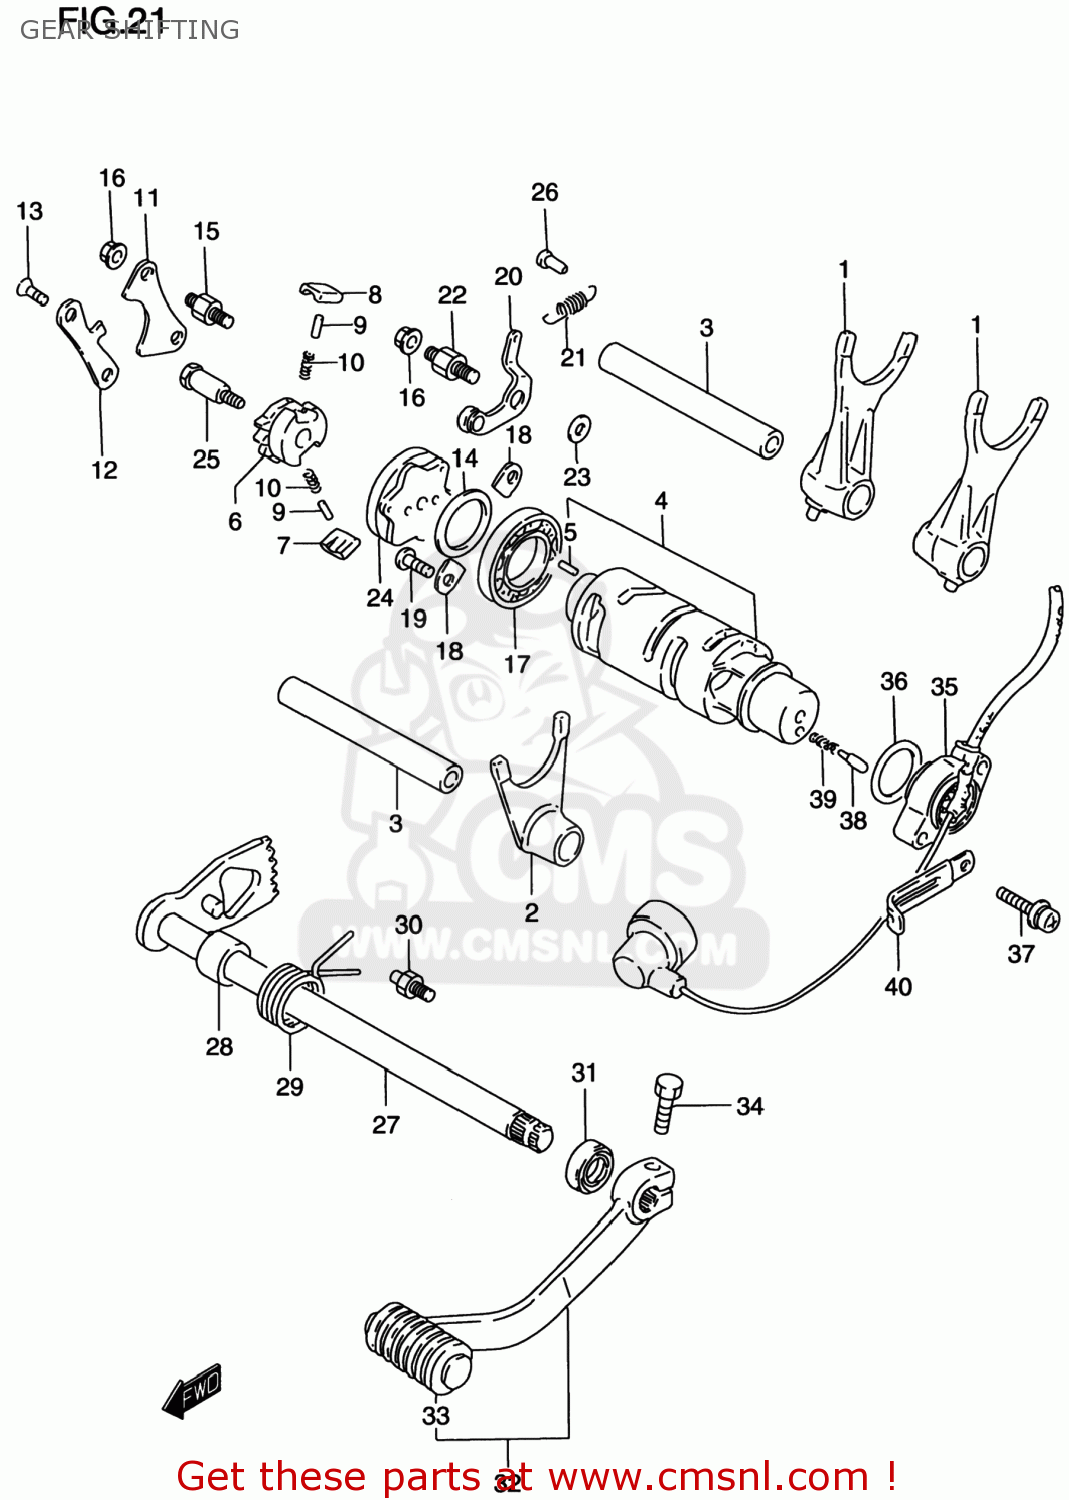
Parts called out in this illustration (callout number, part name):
1	FORK,GEAR SHIFT NO.1
2	FORK,GEAR SHIFT NO.2
3	SHAFT,GEAR SHIFT FORK(L:115)
4	CAM,GEAR SHIFT
5	PIN
6	GEAR,GEAR SHIFT CAM DRIVEN
7	PAWL,GEAR SHIFT NO.1
8	PAWL,GEAR SHIFT NO.2
9	PIN(5X8)
10	SPRING
11	LIFTER,GEAR SHIFT POLE
12	GUIDE,GEAR SHIFT CAM
13	SCREW
14	WASHER(25X32X3)
15	BOSS,SHIFT PAWL LIFTER
16	NUT
17	BEARING(25X47X8)
18	RETAINER
19	SCREW
20	STOPPER,GEAR SHIFT CAM
21	SPRING
22	SUPPORT,CAM STOPPER ARM
23	WASHER
24	PLATE,GEAR SHIFT CAM
25	PIN,SHIFT CAM DRIVEN GEAR
26	RIVET
27	SHAFT,GEAR SHIFT
28	SPACER(12X20X15.3)
29	SPRING
30	STOPPER,GEAR SHIFT CAM
31	OIL SEAL
32	LEVER ASSY,GEAR SHIFT
33	RUBBER,GEAR SHIFT PEDAL
34	BOLT
35	BASE,NEUTRAL SWH TERMINAL
36	O RING(D:2.4,ID:25.7)
37	SCREW
38	PIN(5X15.5)
39	SPRING
40	CLAMP(L:65)
